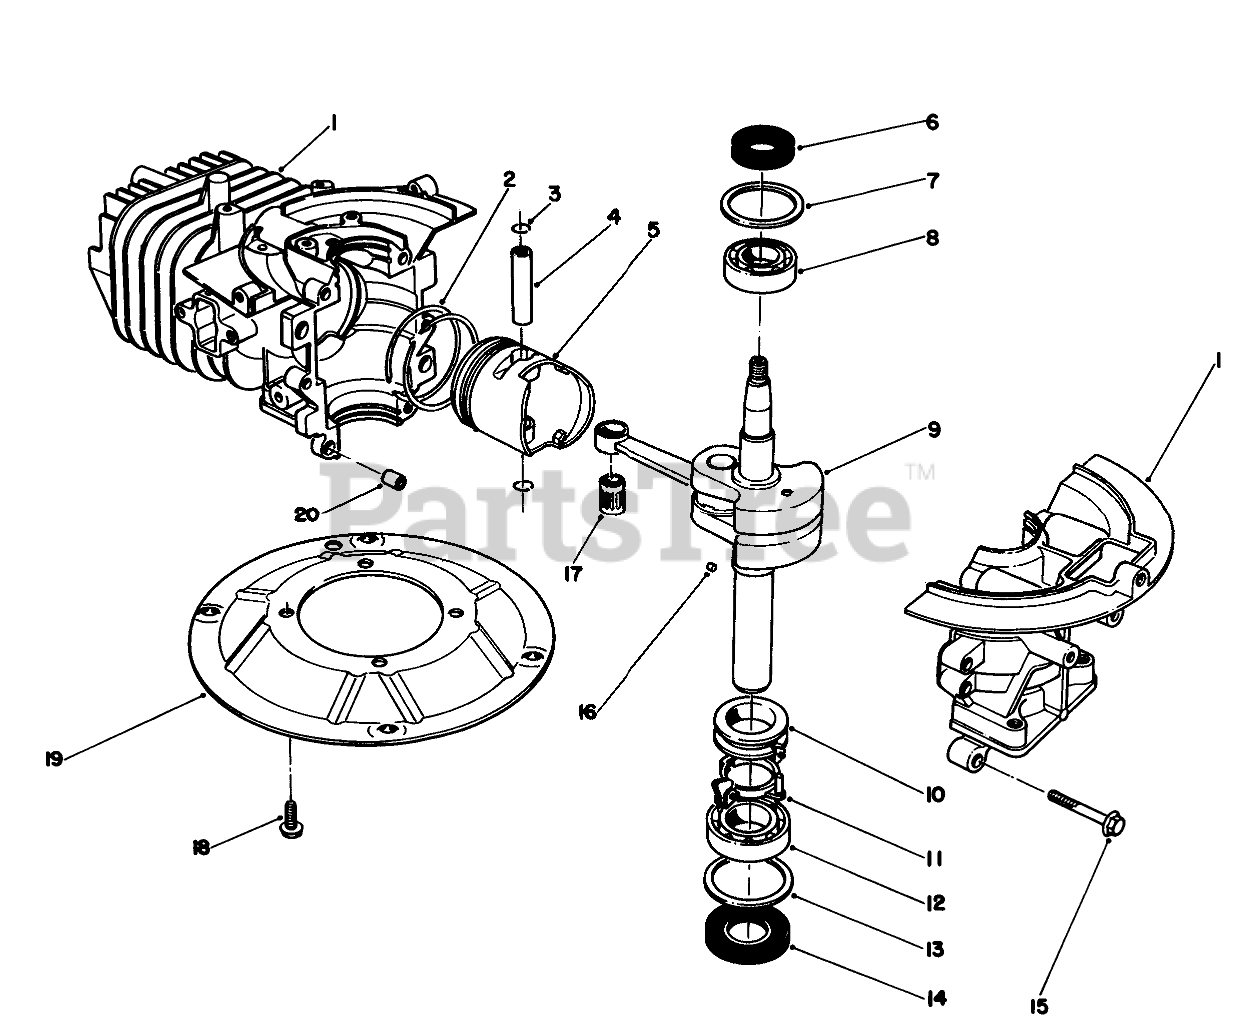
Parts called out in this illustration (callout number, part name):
1	CRANKCASE
1	SCREW
2	RING SET
3	FLYWHEEL
4	PIN-PISTON
5	Piston
5	COIL-MAGNETO
6	OIL SEAL
6	CLAMP
7	WASHER-UPPER
7	Sparkplug
8	BEARING-UPPER
8	CAP-SPARKPLUG
9	Pin-Wrist
10	SPACER
11	BRACKET
12	LOWER BRG
13	WASHER-LOWER
14	SEAL-OIL
17	BEARING
19	PLATE-MOUNTING
